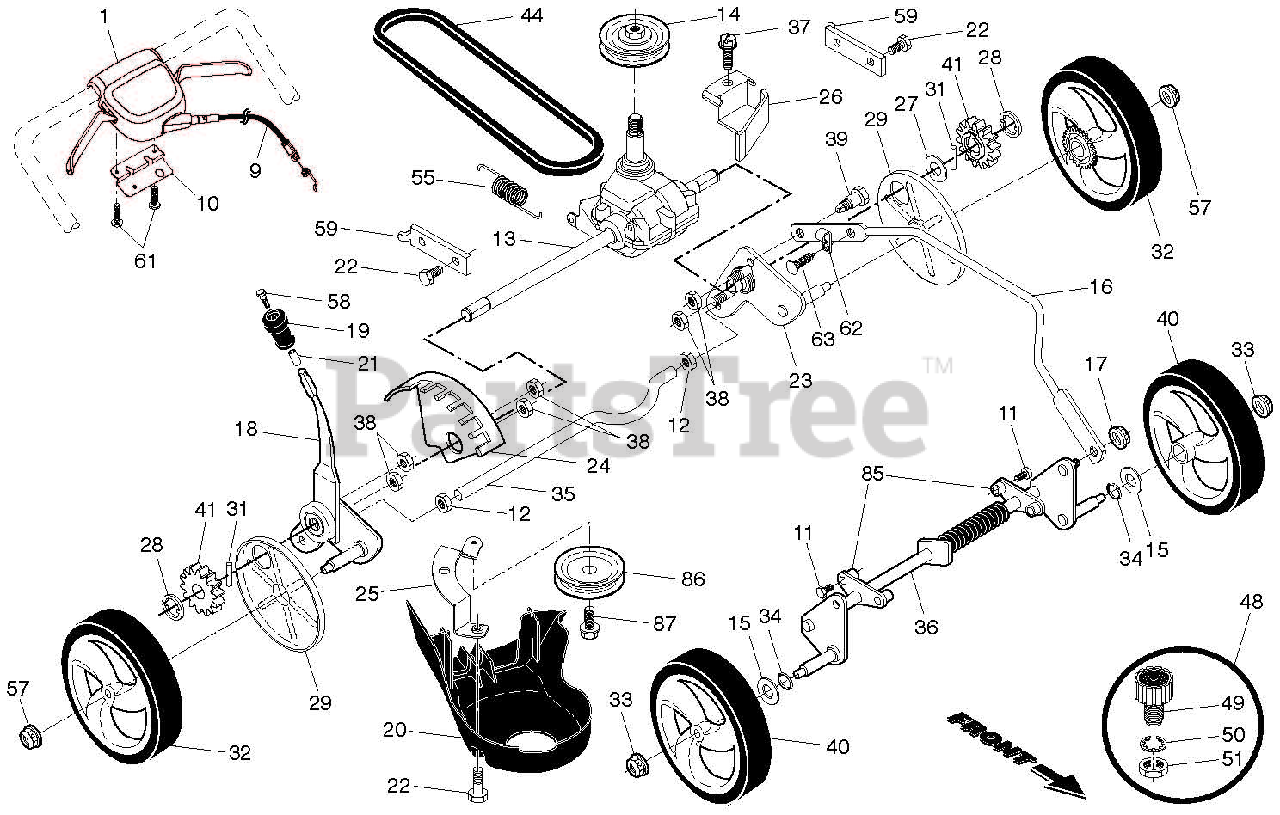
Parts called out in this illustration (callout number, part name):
1	DRIVE CONTROL ASSEMBLY
10	MOUNTING BRCKT, DRIVE CONTROL
11	Screw, Rear Baffle
12	NUT, HEX
13	GEARCASE ASSEMBLY, COMPLETE
14	PULLEY, DRIVE
15	Washer, Flat
16	ROD, CONNECTING
17	Nut, Hex
18	KIT, SELECTOR ASSEMBLY
19	KNOB, WHEEL ADJUSTER
20	DEBRIS SHIELD
22	BOLT.5/16-18HEX.WHS.HD.LCKSERR
23	WHEEL AXLE ASSEMBLY, LH
24	BRACKET, HEIGHT ADJUSTMENT
25	MOUNTING BRCKT, DEBRIS SHIELD
26	BELT KEEPER
27	Washer 17/32 x 3/4 x 16 Ga.
29	COVER, DUST, WHEEL
31	Pawl, Drive
32	WHEEL & TIRE ASSEMBLY, REAR
33	Nut, Hex, Flangelock 3/8-16
35	AXLE, REAR
36	AXLE, FRONT
37	SCREW, HI-LO THREAD #12 X 5/8
38	LOCKNUT, HEX 1/4-20
40	WHEEL & TIRE ASSEMBLY, FRONT
44	BELT, DRIVE
48	KIT, WATER WASHOUT ASSEMBLY
49	FITTING, WATER WASHOUT
50	WASHER, LOCK, INTERNAL TOOTH
51	LOCKNUT, HEX, WITH O-RING
55	SPRING, TENSION
57	Flanged Locknut, Hex
58	BOLT, SHOULDER
59	SUPPORT BRACKET
62	Clip, Cable
63	FASTENER, PUSH
85	SUPPORT BRACKET, FRONT AXLE
86	PULLEY, IDLER
